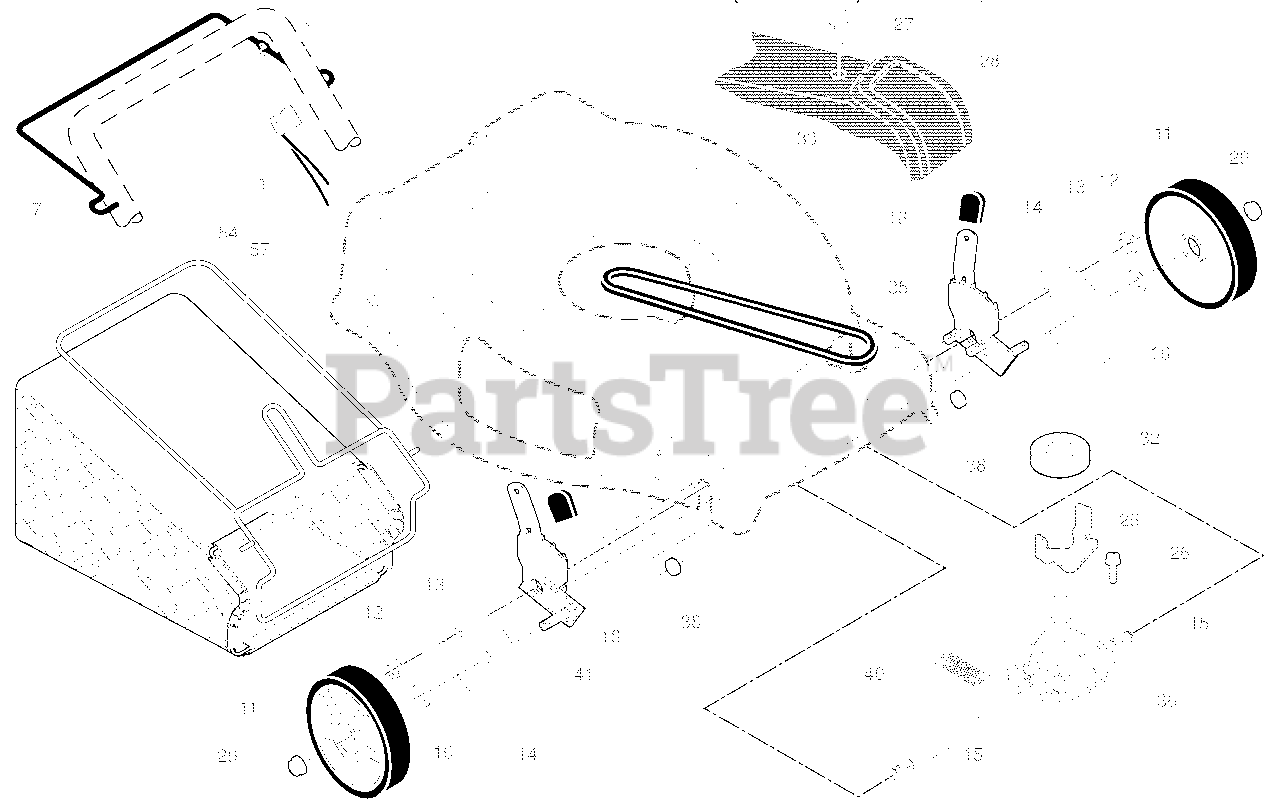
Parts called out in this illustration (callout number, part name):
1	CABLE, DRIVE CONTROL
7	CONTROL BAR, DRIVE
11	WHEEL & TIRE ASSEMBLY
14	DUST COVER
15	Pawl, Drive
16	Washer, Flat 3/8
18	Selector Knob
25	BELT KEEPER
26	SCREW, HI-LO THREAD #12 X 5/8
27	Pan Head Tapping Screw #10-24
28	DRIVE COVER
29	Nut, Hex
32	DRIVE PULLEY
35	WHEEL ADJUSTER, FRONT LH W/BRG
36	GEARCASE ASSEMBLY, COMPLETE
38	LOCKNUT, HEX 1/4-20
41	WHEEL ADJUSTER, FRONT RH W/BRG
54	GRASSBAG
57	FRAME, GRASSBAG
